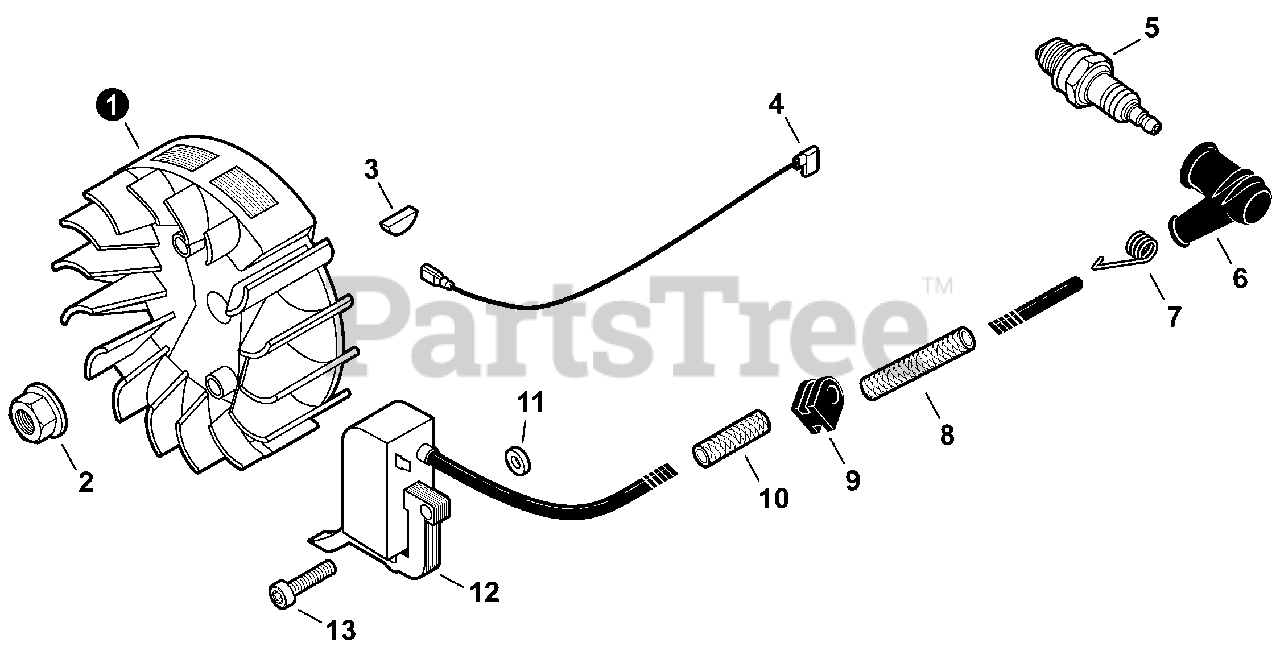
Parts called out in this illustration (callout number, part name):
1	FLYWHEEL
2	NUT, FLANGE M8
3	KEY, WOODRUFF
5	SPARK PLUG - BPMR-8Y
6	CAP, SPARK PLUG
7	TERMINAL, SPARK PLUG
8	SLEEVE, INSULATOR HST-10 7×0.8×40
9	GROMMET, HT CORD
10	SLEEVE, INSULATOR 7×8.6×30
11	WASHER 5.2×12×3
12	COIL, IGNITION
13	BOLT, TORX 5×20
